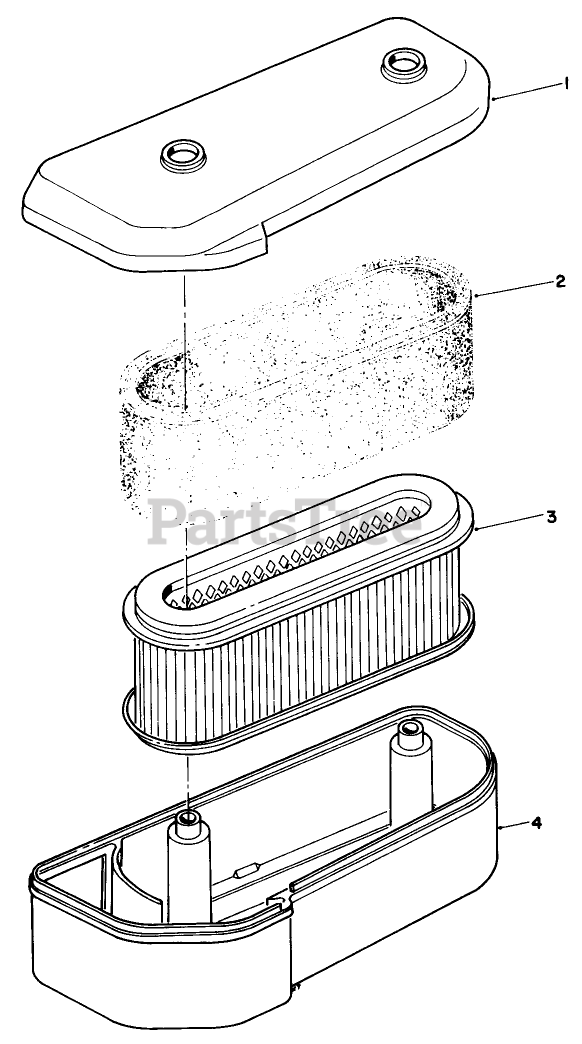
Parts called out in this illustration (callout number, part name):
1	CAP-Air Filter
2	Element
3	Element
4	CASE-Air Filter
